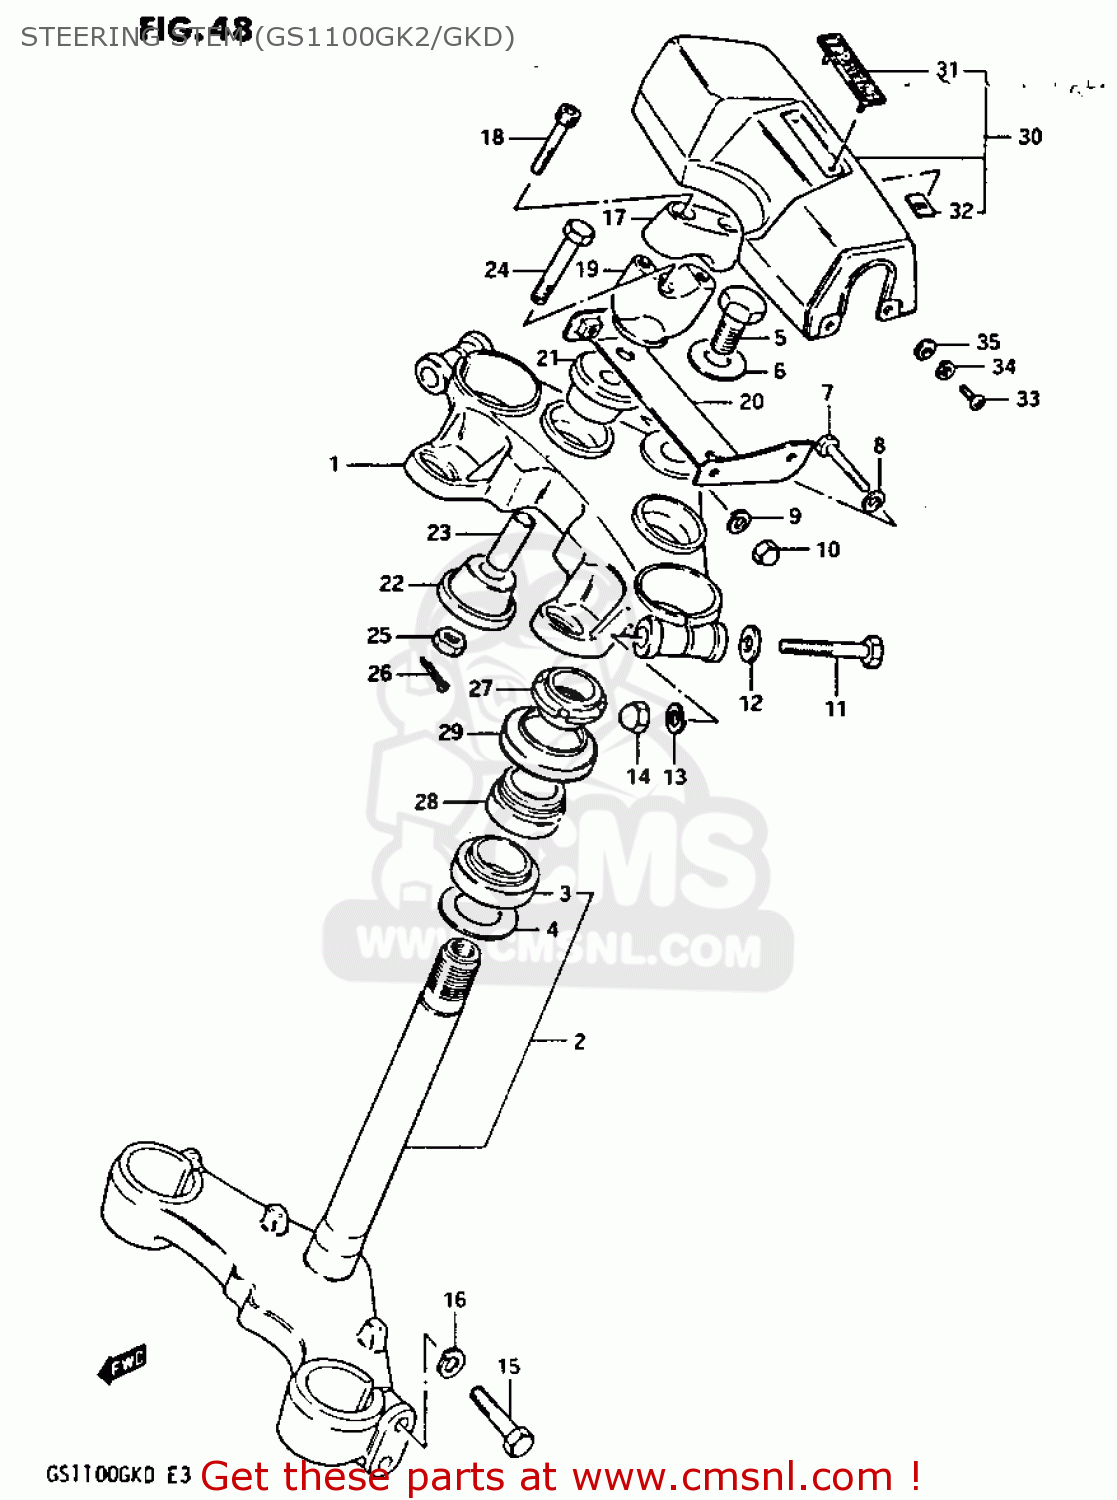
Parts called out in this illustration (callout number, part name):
1	HEAD,STEERING STEM
2	STEM,STEERING
3	BEARING(30X55X17)
4	WASHER,THRUST
5	NUT,STEM HEAD
6	WASHER,STEERING STEM
7	BOLT 8X50
8	WASHER
9	WASHER,LOCK,8.
10	NUT,M8X1.25X12
11	BOLT 10X55
12	WASHER 10MM
13	WASHER,LOCK
14	NUT 10MM
15	BOLT 8X40
16	WASHER,LOCK
17	HOLDER,HANDLEBAR
18	BOLT, REAR (8X30)
19	HOLDER,HANDLEBAR
20	BRACKET,STEERING HEAD
21	CUSHION
22	CUSHION HOLDER
23	SPACER(10.2X14X46)
24	BOLT,HANDLE HOLDER
25	NUT
26	COTTER PIN
27	NUT,STEERING STEM
28	TAPER,ROLLER BEARING
29	DUST SEAL,STEERING UPR
30	PAD,HANDLE
31	EMBLEM,HANDLE COVER PAD
32	NUT
33	SCREW
34	LOCK WASHER
35	WASHER
